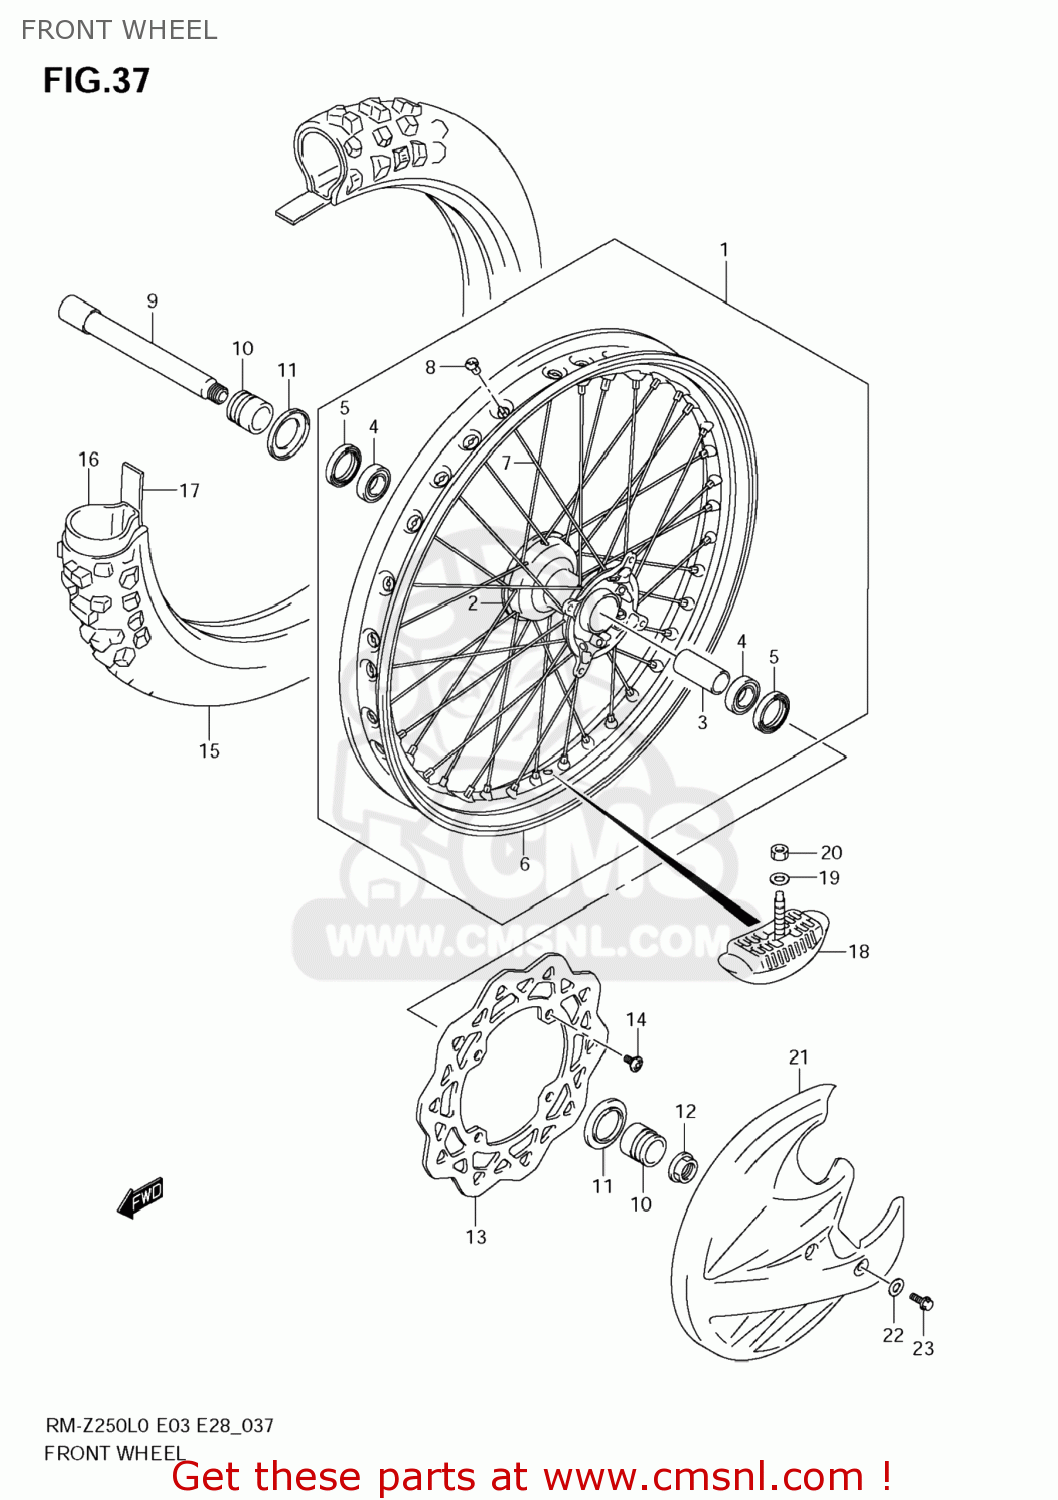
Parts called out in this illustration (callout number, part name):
1	WHEEL ASSY,FR
2	HUB,FR
3	SPACER,FR HUB BEARING
4	BEARING(22X39X9)
5	SEAL,OIL(30X40X7)
6	RIM,FR WHEEL
7	SPOKE,FR WHEEL
8	NIPPLE,FR WHEEL
9	AXLE,FR
10	SPACER,FR AXLE
11	COVER,FR AXLE SPACER
12	NUT
13	DISC,FRONT BRA
14	SCREW(6X13.5)
15	TIRE,FR(80/100 21)
16	TUBE ASSY,WHEEL INNER
17	PROTECTOR,WHL INR TUBE
18	STOPPER,BEAD
19	WASHER
20	NUT
21	COVER,FR BRAKE DISC
22	WASHER,FR BRAKE DISC COVER
23	BOLT(6X12)
